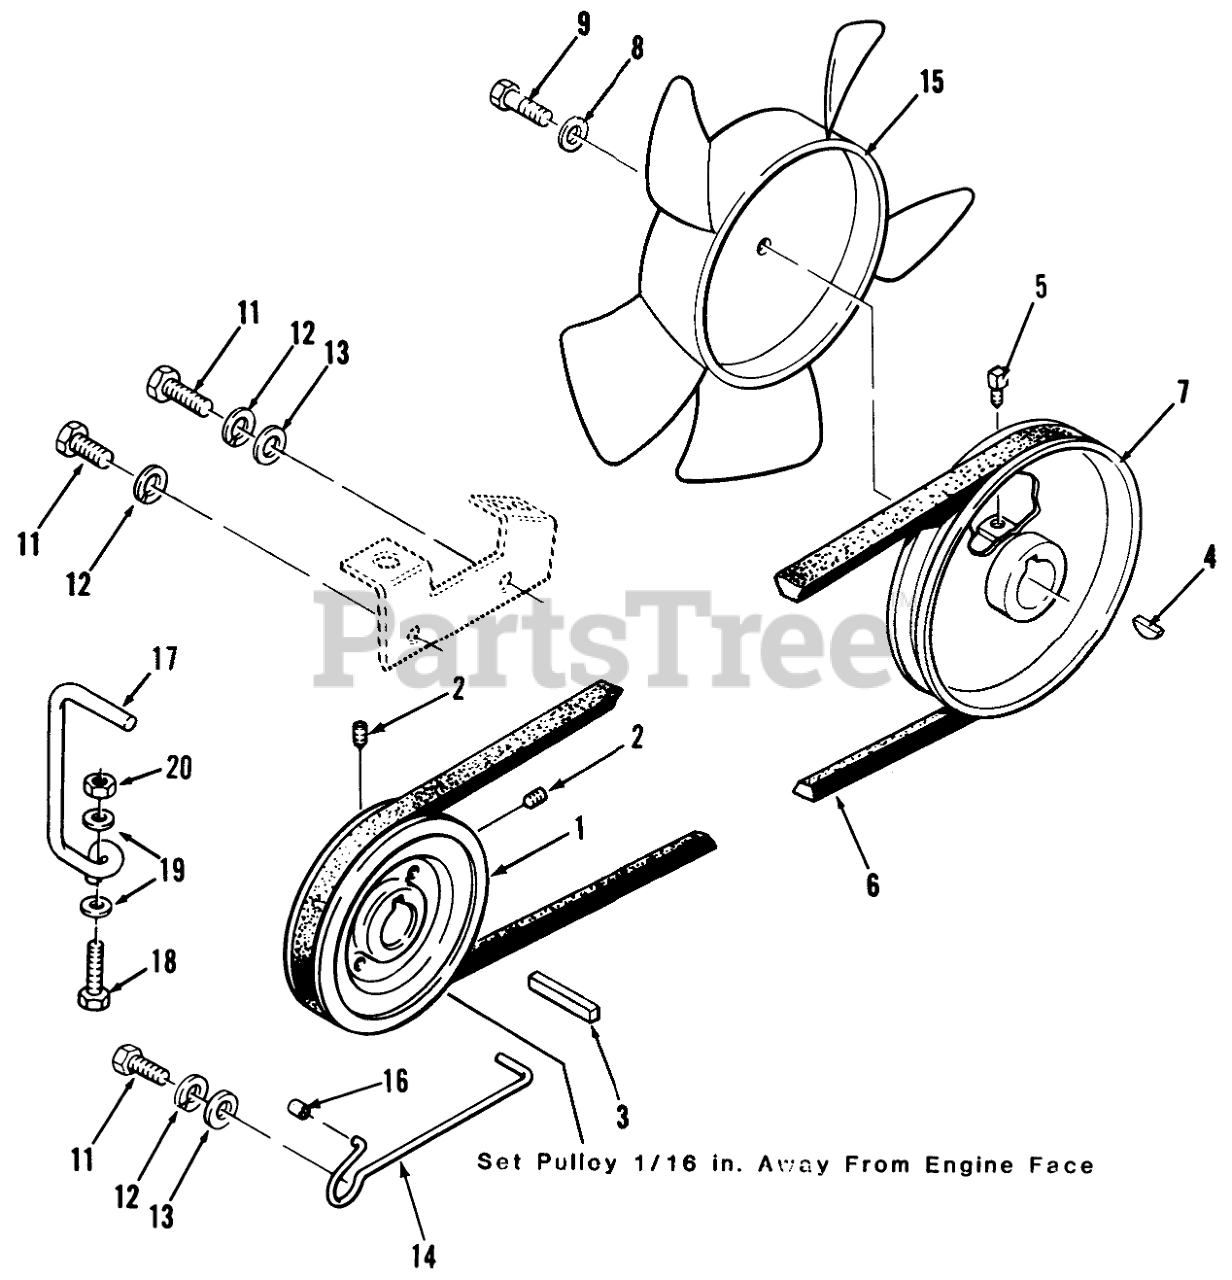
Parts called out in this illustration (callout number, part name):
1	PULLEY
2	Set Screw
4	KEY-HI PRO
5	Set Screw
6	Belt-Drive
7	PULLEY-TRANSMISSION
8	WASHER
9	H H C S
11	7/16-14 x 1 1/4 Bolt
12	LOCKWASHER
13	WASHER
14	GUIDE BELT
15	NYLON FAN-L-CW
17	GUIDE-BELT BOTTOM
18	Bolt
19	Collar
20	Nut
